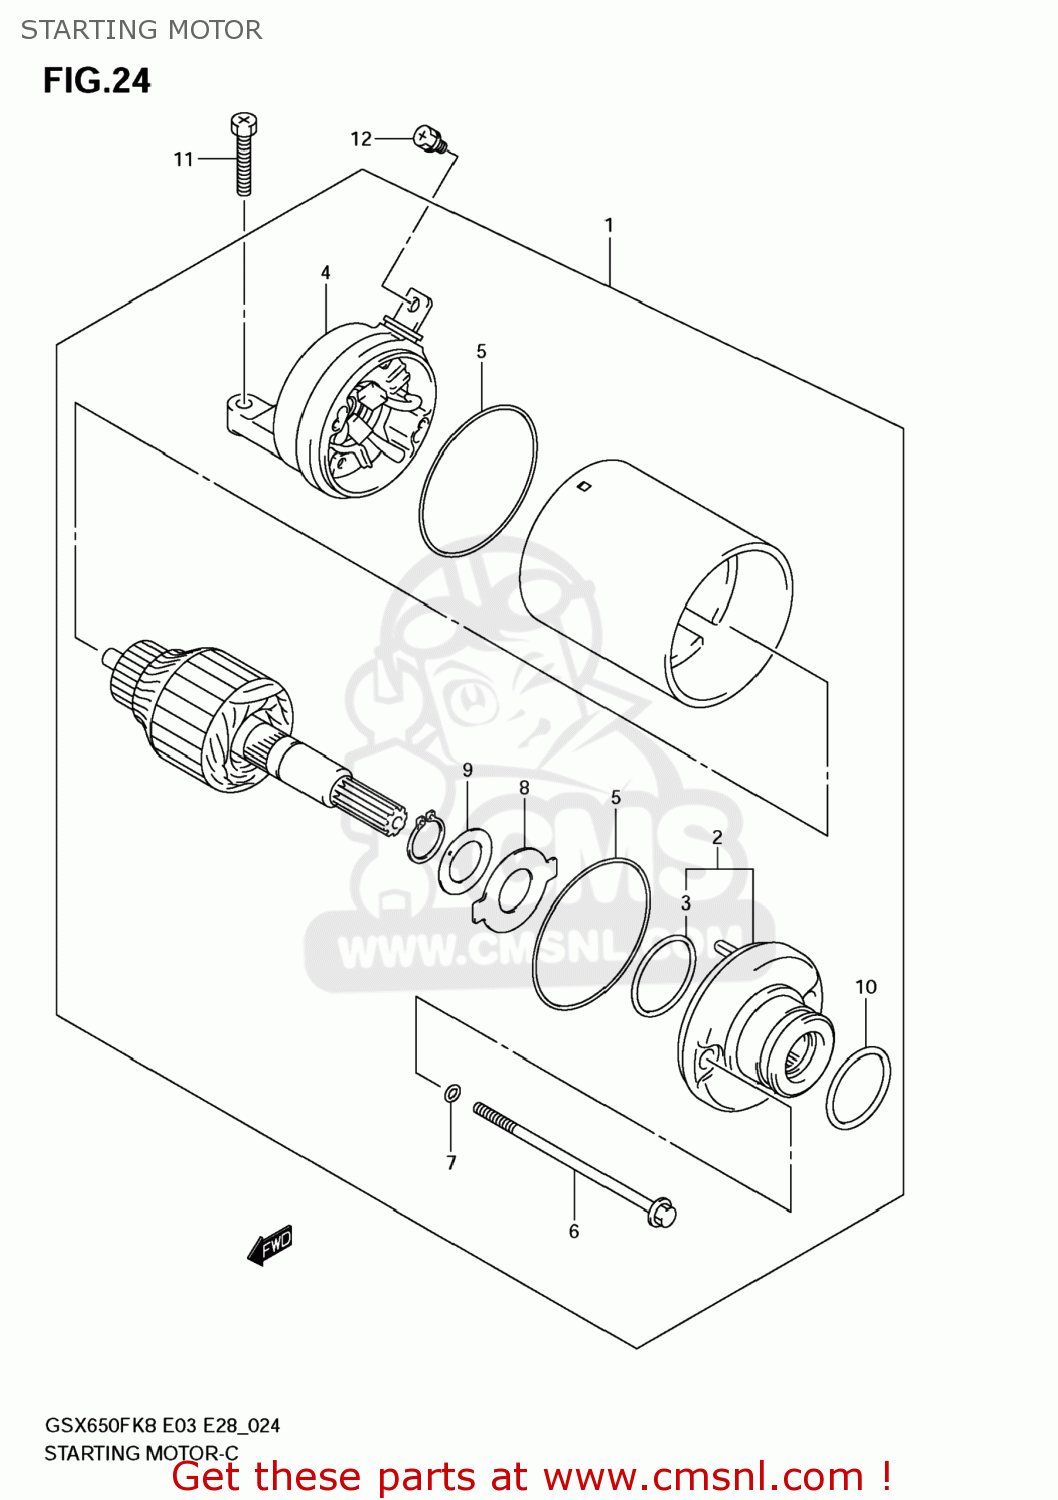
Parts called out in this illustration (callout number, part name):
1	MOTOR ASSY,STARTING
2	BRACKET
3	SEAL,OIL
4	FRAME ASSY,COMMUTATOR END
5	O RING
6	BOLT
7	O RING
8	PLATE,LOCK
9	SHIM
10	O RING(D:3,ID:24.5)
11	BOLT(6X25)
12	SCREW(5X8)
